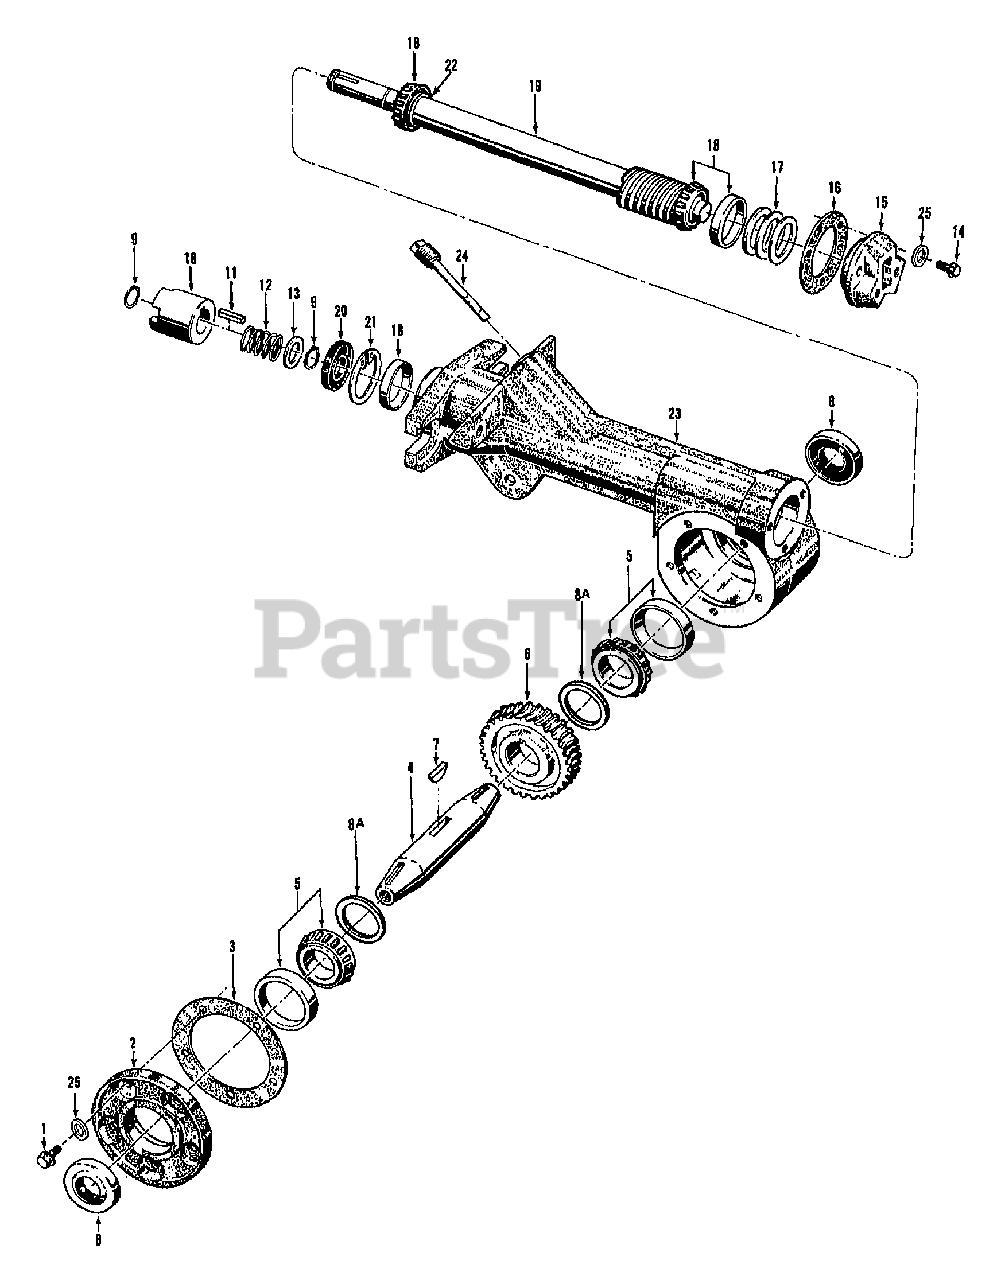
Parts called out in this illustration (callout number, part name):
1	SCR-HH 1/4-20X.625
2	COVER-W/5 SCRS(TLR) (9780 REF.#1)
3	GASKET-TILLER COVER .010"
3	GASKET-TILLER COVER .030"
4	SHAFT-TILLER
5	KIT-BEARING CUP & CONE (CONE & CUP SOLD AS SET ONLY)
6	GEAR-WORM MACH
7	KEY-WOODRUFF .250X1.01
8	SEAL-OIL TILLERSHAFT
8A	WASHER-1.75X1.260X.054
9	RING-RETAIN EXT .707 ID (SNAP RING)
10	KIT-CLUTCH DOGS TILLER
11	KEY-.188 SQX1.0
12	SPRING (TC)
13	SHIM-1.0X.7656X.062
14	SCR-HFLK 1/4-20X.875
15	CAP-REAR #1115
16	GASKET-BRG COVER
17	SHIM-1.75X1.5X.01
17	SHIM-1.75X1.5X.03
17	SHIM-1.75X1.5X.005
17	SHIM-1.75X1.5X.062
18	KIT-BRG CONE&RACE-DRIVESHAFT (CONE AND CUP SOLD AS SET ONLY)
19	KIT-TLR DRIVESHAFT HORSE 3
20	SEAL-OIL DRIVESHAFT, FRONT
21	RING-RETAINING 5000-181 (SNAP RING)
22	WASHER-#1.25X.75X.06 (DRIVE SHAFT)
23	HSG-TLR ATT W/SLEEVE/RACEH3
24	ASSM-OIL DIPSTICK
25	WASHER, NYLON 1/4" NOT REUSABLE
